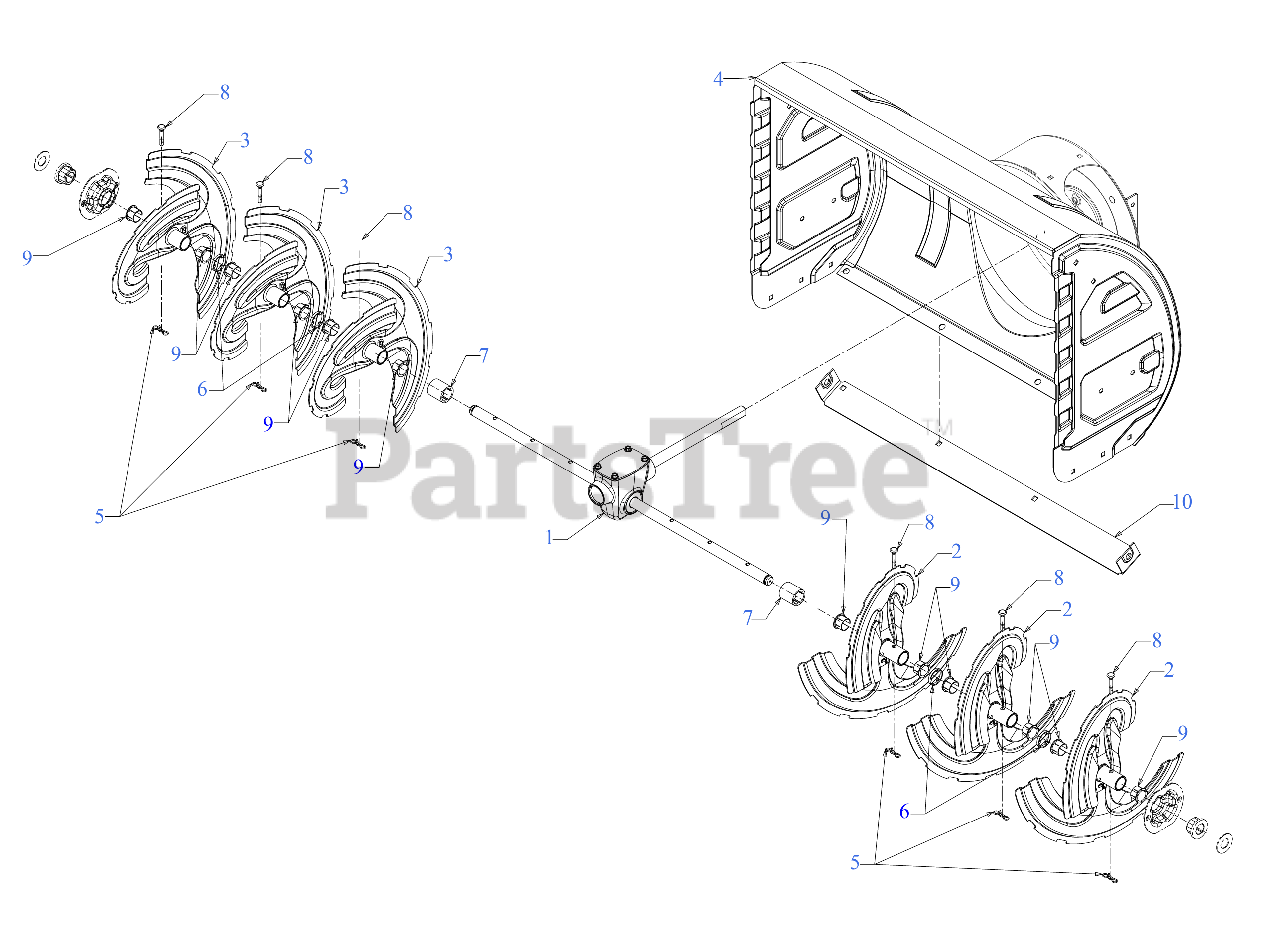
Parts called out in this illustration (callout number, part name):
1	30" AUGER GEARBOX ASSEMBLY
5	BOW TIE COTTER PIN 1/4-5/16
6	SPCR 1.25 OD x 75IDX2.00LG
7	SPACER 1.25OD x .75ID x 1.312 LG
8	SHEAR PIN .25 x 1.50 GR2
9	FLANGE BUSHING
